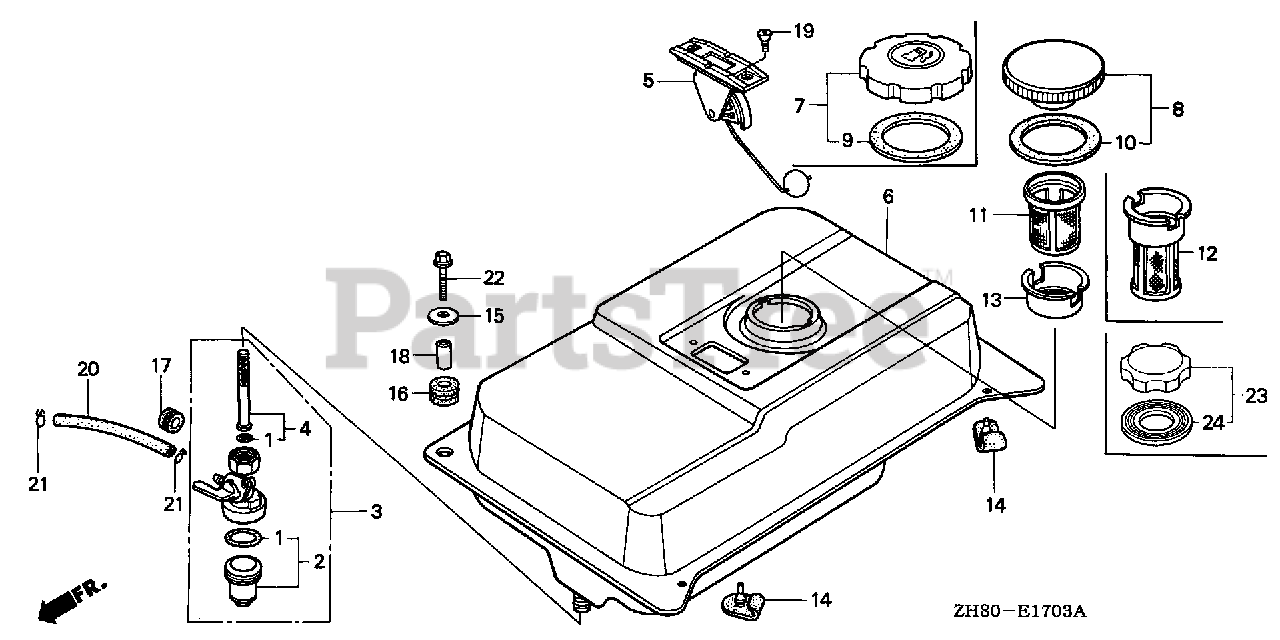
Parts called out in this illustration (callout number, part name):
1	GASKET SET, PETCOCK (CONTAINS 1 LARGE & 1 SMALL. USE AS NEEDED)
2	CUP, FUEL STRAINER
3	PETCOCK ASSY.
4	SCREEN SET
5	METER ASSY., FUEL
6	TANK, FUEL *T68* (TSURUMI BLUE)
6	TANK, FUEL *Y131* (LIGHTNING YELLOW)
6	TANK, FUEL *NH1* (BLACK)
6	TANK, FUEL *R280* (POWER RED)
7	CAP, FUEL FILLER (BLACK)
8	CAP, FUEL FILLER (BLACK)
9	GASKET, FUEL FILLER CAP (39X58X3)
10	GASKET, FUEL FILLER CAP (39X58X3)
11	FILTER, FUEL
12	FILTER, FUEL
13	HOLDER, FUEL FILTER
14	RUBBER, TANK MOUNTING
15	WASHER, AIR DUCT
16	RUBBER, CONTROL BOX
17	RUBBER, FUEL (9X15X10)
17	RUBBER, FUEL (9X15X20)
18	COLLAR, CONTROL BOX
19	SCREW, FLAT (5X10)
20	BULK HOSE, FUEL (4.5X3000) (4.5X95)
20	BULK HOSE, FUEL (4.5X3000) (4.5X150)
20	BULK HOSE, FUEL (4.5X3000) (95001-450(95001-45001-60M)
21	CLIP, TUBE (B8)
22	BOLT, FLANGE (6X20)
23	CAP, FUEL FILLER (CHROME PLATED)
23	CAP, FUEL FILLER (CHROME PLATED)(TOUYOUSYA)
24	GASKET, FUEL FILLER CAP (39X62X3) (TOUYOUSYA)
